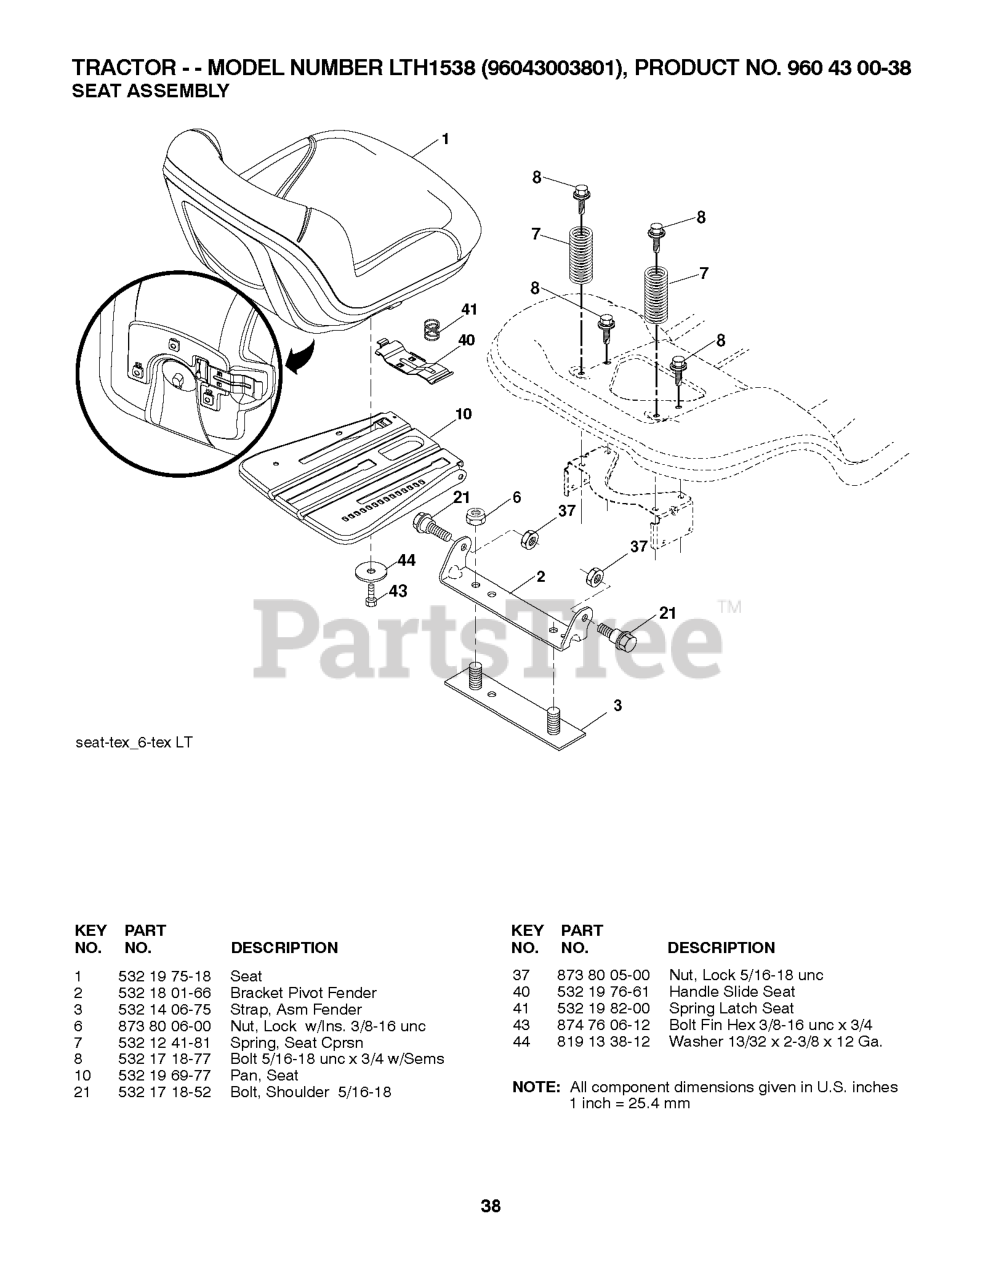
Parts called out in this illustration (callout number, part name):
1	SEAT.TH130.GRY.MILSCO.
2	BRKT.PIVOT.FENDER
3	STRAP
6	NUT
7	SPRING COMPRESSION
8	BOLT.5/16-18UNCX3/4 W/SEMS.BLK
10	PAN.ASM.SEAT.3PT
21	BOLT.SHOULDER.5/16-18
37	NUT.71038.31-18.HEX.NYLOCK
40	HANDLE.SLIDE.SEAT.TEX.BLACK
41	SPRING.LATCH.SEAT.TEX
44	WASHER 13/32 X 2-3/8 X 12GA
